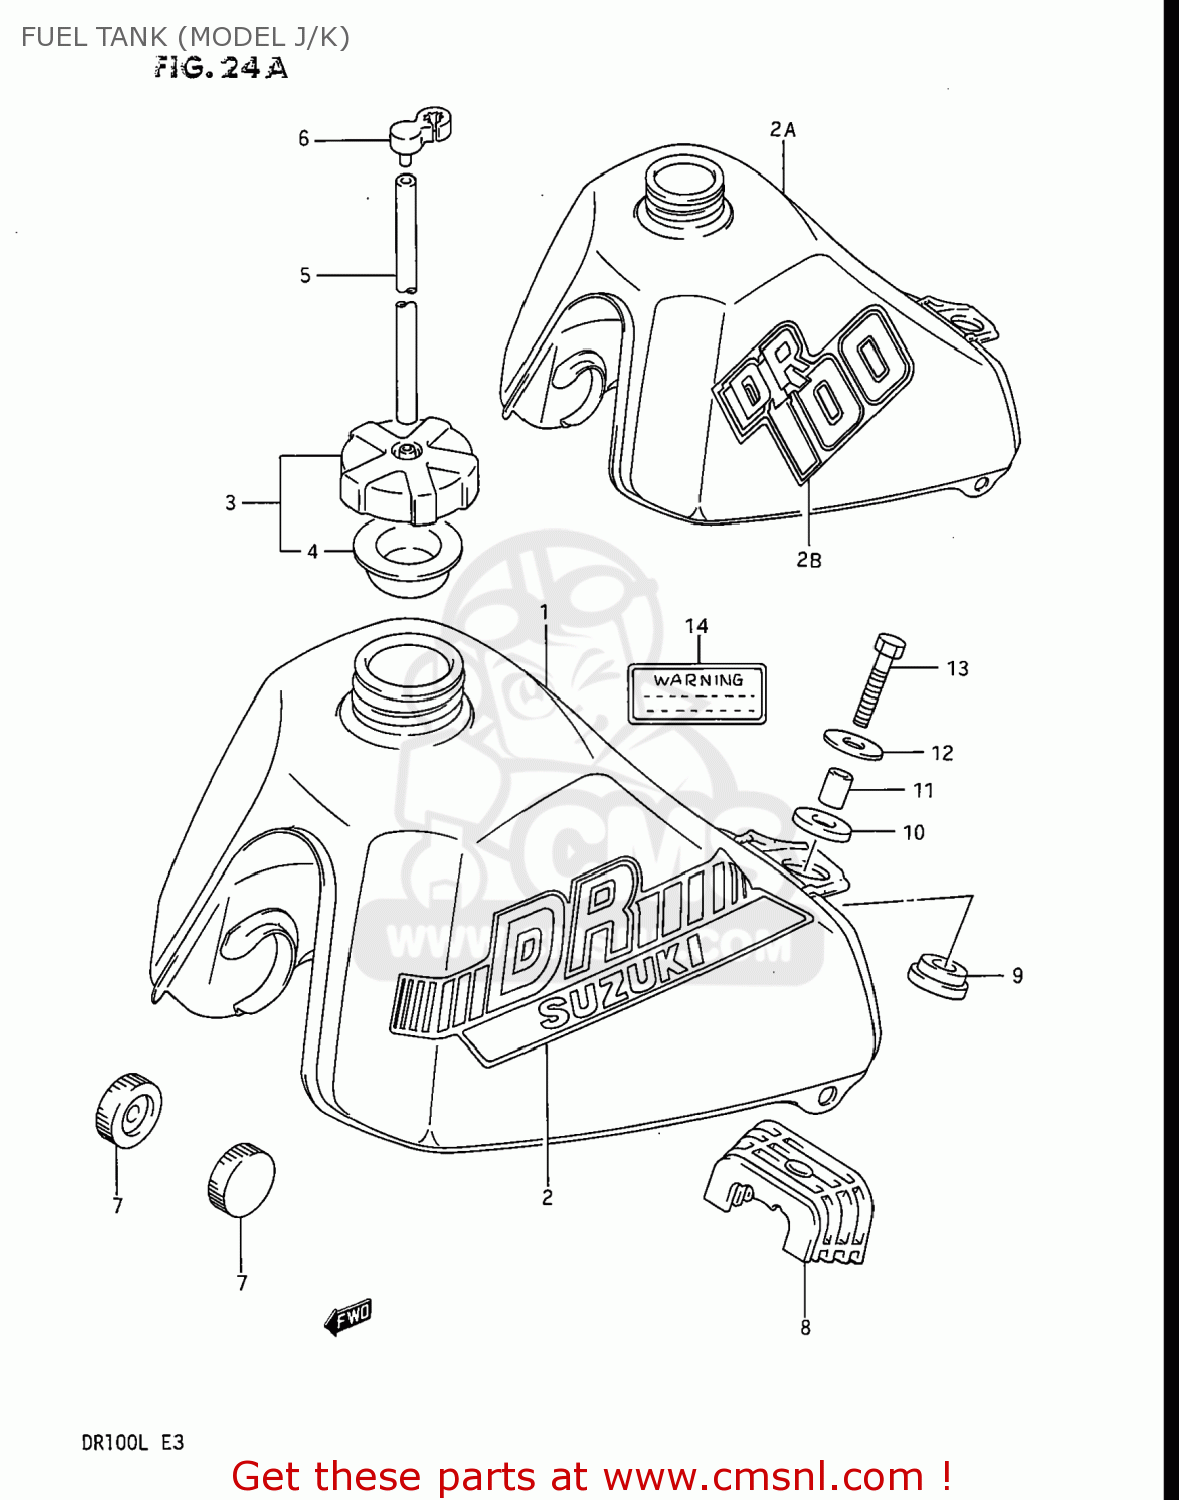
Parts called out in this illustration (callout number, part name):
1	TANK ASSEMBLY,FUEL
2	TAPE SET,FUEL TANK
2A	TANK ASSEMBLY,FUEL
2B	EMBLEM SET,FUEL TANK
3	CAP SET,FUEL TANK
4	GASKET (NAS)
5	HOSE
6	CLAMP,FUEL TANK BREATHER HOSE
7	CUSHION
8	CUSHION,FUEL TANK
9	CUSHION
10	CUSHION
11	SPACER(8.5X12X19)
12	WASHER (8.5X29X1.6)
13	BOLT
14	LABEL (WARNING)
